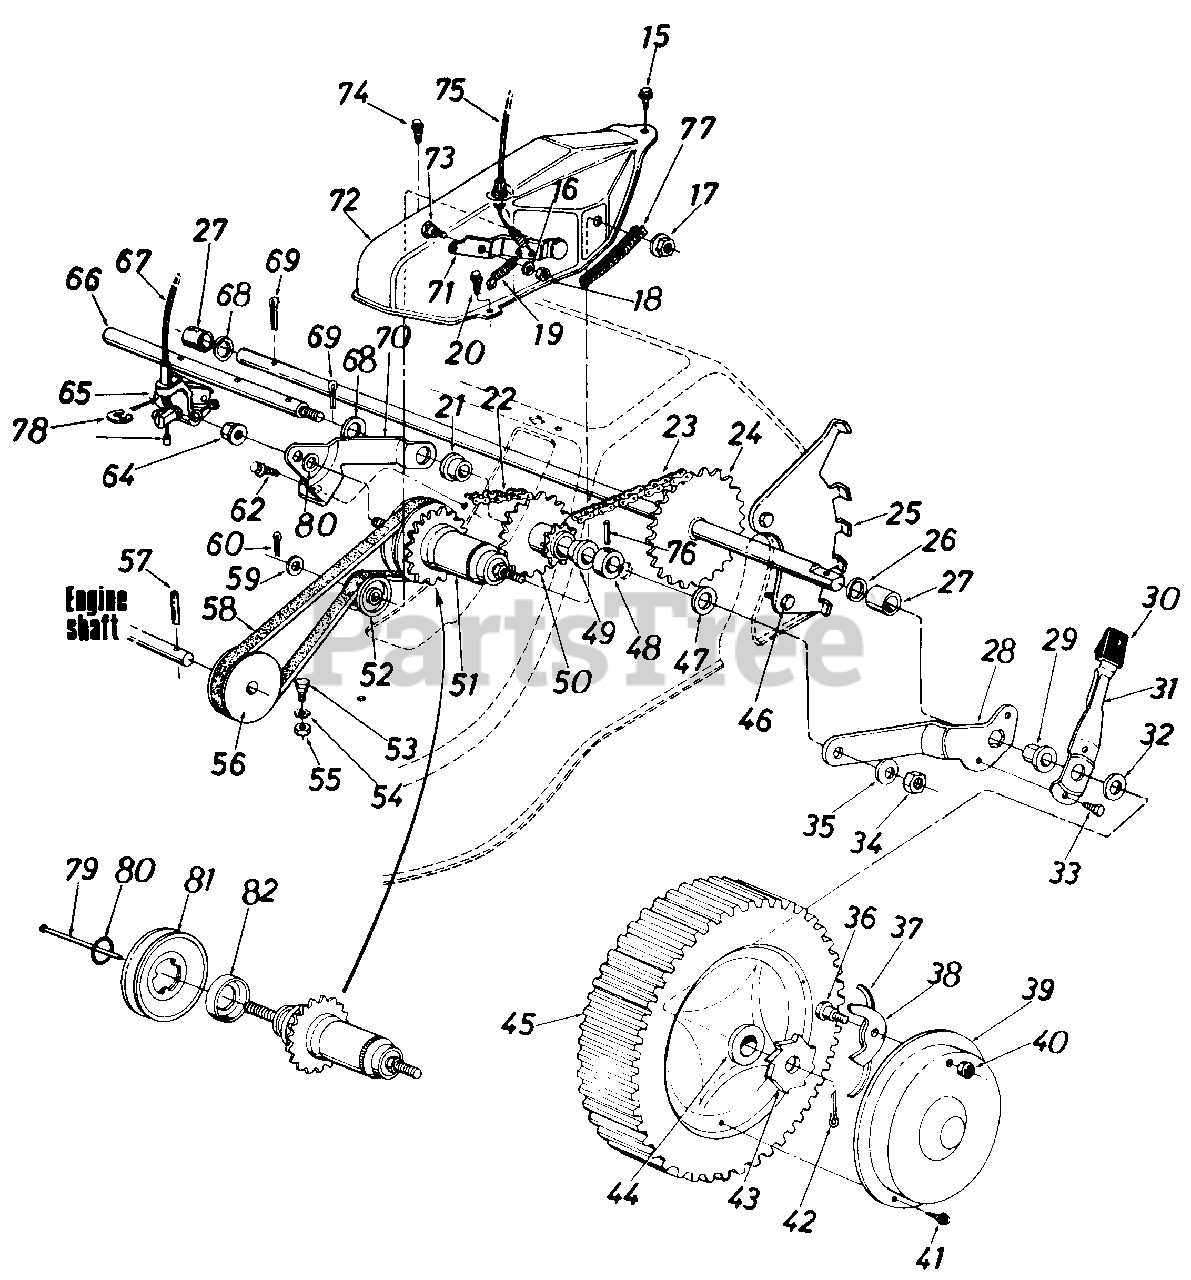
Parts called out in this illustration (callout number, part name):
15	Hex Drilling Scr. #10 x .50" Lg.
16	L-Wash. 1/4" I.D.
17	Hex Nut 3/8-24 Thd.
18	Hex Nut 1/4-20 Thd.
19	Extension Spring .33" O.D. x 1.12" Lg.
20	Hex Wash. S-Tap Scr. 1/4-20 x .50" Lg.
21	Flg. Brg. .506" I.D. Plastic
22	#48 Chain 1/2" Pitch x 38 Links (Endless)
23	#48 Chain Pitch x 32 Links (Endless)
24	Rear Shaft Ass'y. 20.75"
25	Index Plate Rear L.H.
26	Fl-Wash. .510" I.D. x 1.0"
27	Spacer .740" I.D. x .83" O.D.
28	Pivot Brkt. L.H.
29	Hex Flange Brg. .506" I .D. Plastic
30	Spring Lever Knob
31	Spring Lever
32	Fl-Wash. .531" I.D. x .930"
33	Hex B-Tap Scr. 1/4 x .38"
34	Hex Jam Nut 3/8-16 Thd.
35	Bell-Wash. .400" I.D. x .88"
36	Shld. Bolt .342" Dia. x .268
37	Spring-Nylon
38	Pawl
40	Hex Ins. L-Nut 1/4-20 Thd.
41	Pan Hd. Tap Scr. #12 x .50" Lg.
42	Cotter Pin 118" Dia. x 1.0"
43	Ratchet Wheel 1.62" O.D.
44	Fl-Ball Brg. 1/2" I.D.
45	Wheel Ass'y. Comp. 8 x 1.75
46	Hex L-Wash. Hd. AB-Tap Scr. 1/4 x .62" Lg.
47	Bell-Wash. .400" I.D. x 1.13" O.D.
48	Spacer .505" I.D. x .88" O.D.
49	Flg. Brg. .506" I.D. Plastic
50	9 and 21 Tooth Sprocket Ass'y.
51	Shimano 3-Sp. Hub w/18 Tooth Sprocket
52	Fl-ldler Plastic 1.62" Dia.
53	Shld. Bolt .437" Dia. x .180
54	L-Wash. 5/16" I.D.
55	Hex Nut 5/16-18 Thd.
56	1/7" "V"-Engine Pulley .50" I.D. x 2.80" ) D.
57	Spring Pin Splr 3/16" Dia. x 1.50" Lg
58	"V"-Belt 1/2" X 26.0" Lg.
59	Fl-Wash. .531" I.D. x .930"
60	Cotter Pin 1/8" Dia. x l.O"
62	Hex Wash. Hd. Tap Scr. 5/16-18 x .75" Lg.
64	Hex Nut 3/8-24 Thd.
65	Shimano 3-Sp. Shift Bell Crank
66	Pulley Shaft 10" Lg.
67	Shimano 3-Sp. Solid Shift Cable
68	Fl-Wash. .531" I.D. x .930"
69	Cotter Pin 3/32" Dia. x l.O"
70	3-Sp. Hub Bracket
71	Idler Bracket Ass'y.
72	3-Sp. Belt Cover
73	Shld. Bolt .375" Dia. x .181
74	Hex TT-Tap Scr. 1/4-20 x .75" Lg.
75	S.P. Cable-53" Lg.-Blue
76	Spring Pin Spir. 3/16" Dia. x 1.0" Lg.
78	Snap Ring
79	Shifting Pin
80	Pulley Snap Ring
81	3/2" V-Pulley 1.375" I.D. x 3.25" O.D.
82	Shimano 3-Sp. Dust Cover
